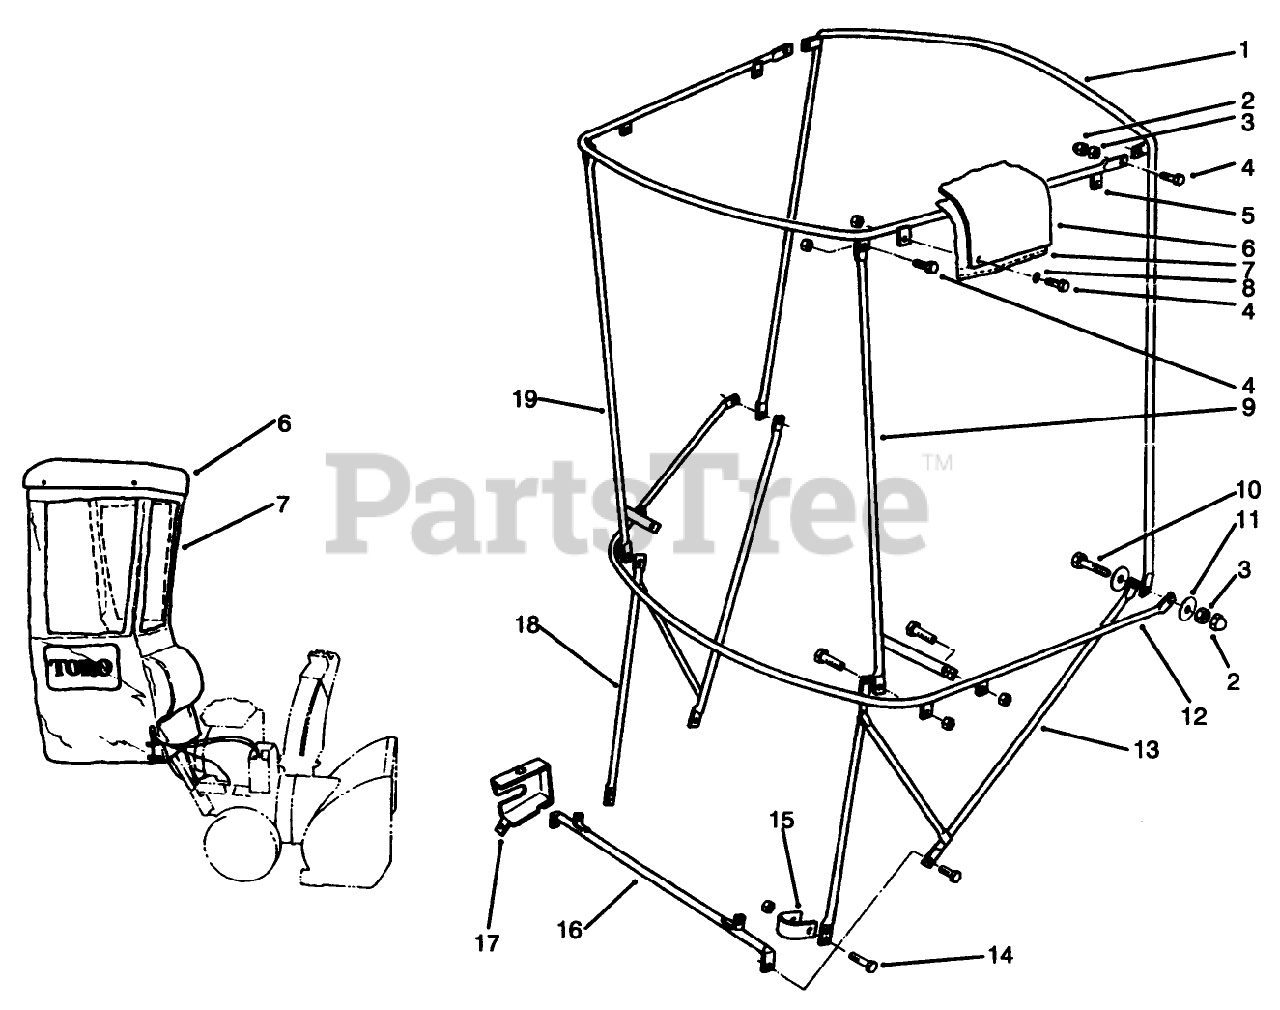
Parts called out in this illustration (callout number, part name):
1	VERTICAL BOW
2	CAPLUG
3	NUT-HEX, SIDE DEFORM
4	SCREW-HH
5	FRAME - TOP
6	Top-Plastic
7	Cover-Vinyl
8	WASHER-FLAT
9	CORNER POST - LH
10	SCREW-HH
11	WASHER-FLAT
12	HORIZONTAL BOW
13	Bracket-LH
14	SCREW-HH
15	CLAMP
16	Bracket-Base
17	COVER-LOCK, LEVER
18	BRACKET-RH
19	CORNER POST - RH
